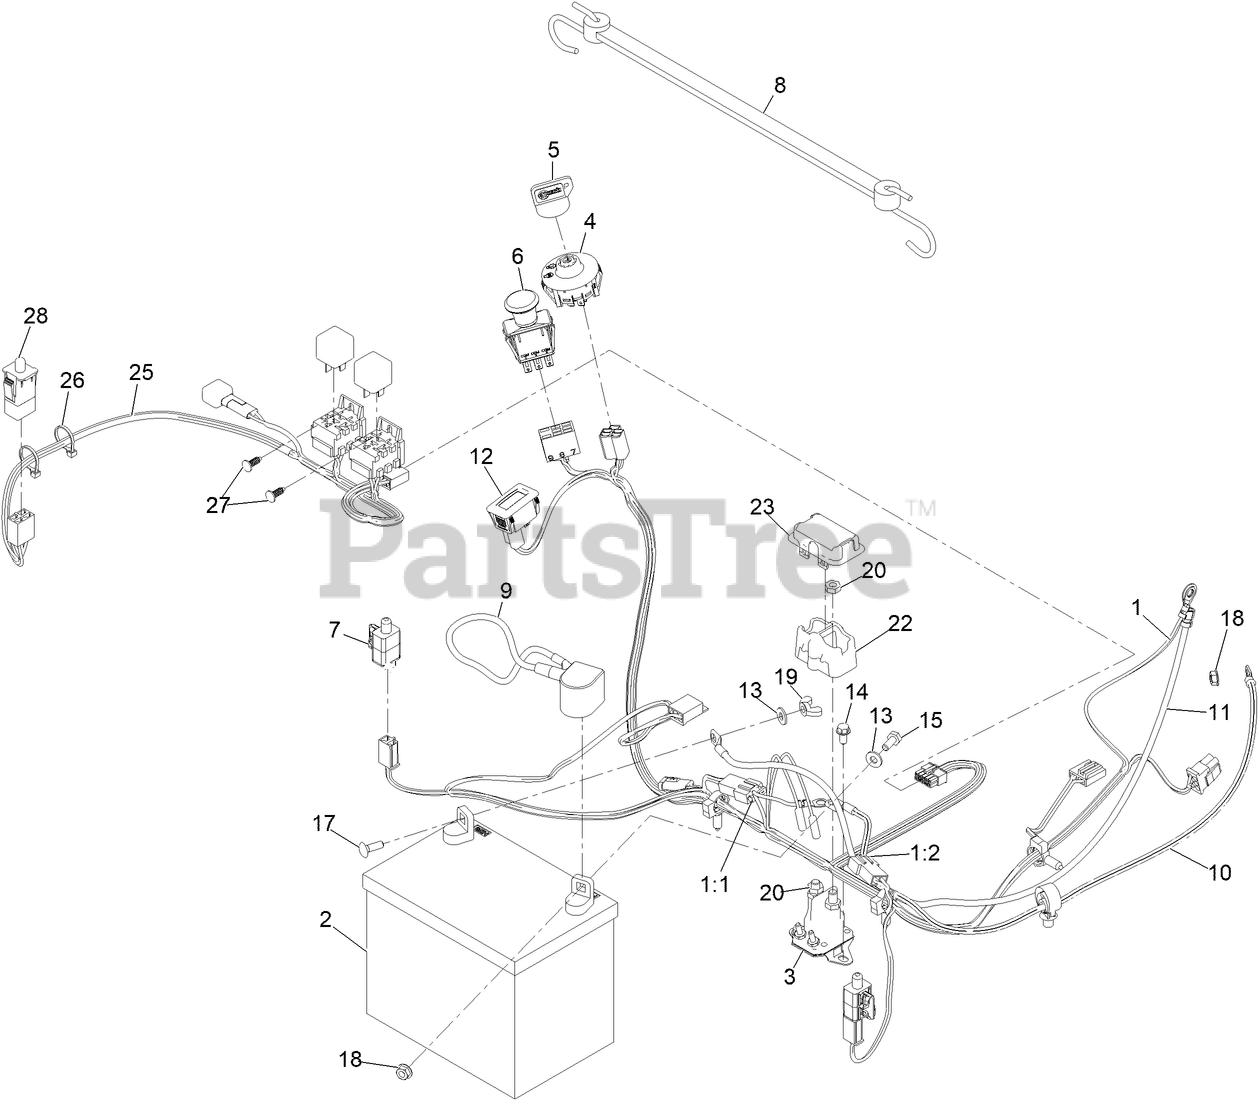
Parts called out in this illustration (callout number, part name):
1	HARNESS-WIRE
1:1	FUSE-BLADE, 15 AMP
1:2	FUSE-BLADE, 25 AMP
2	BATTERY
3	SOLENOID
4	SWITCH-IGNITION
5	KEY-IGNITION
6	SWITCH-PTO
8	STRAP-RUBBER
9	CABLE-BATTERY, POS
10	CABLE-BATTERY, RED (8 GAUGE)
11	CABLE-BATTERY, BLACK
12	HOURMETER
13	WASHER-FLAT
14	SCREW-HWH
15	SCREW-HH
17	BOLT-CARR
19	NUT-WING
20	NUT-JAM
22	COVER-SOLENOID
23	CAP-SOLENOID
25	Harness-Manual Park Brake
26	TIE-CABLE
27	Plug-Plastic
28	SWITCH-DELTA
